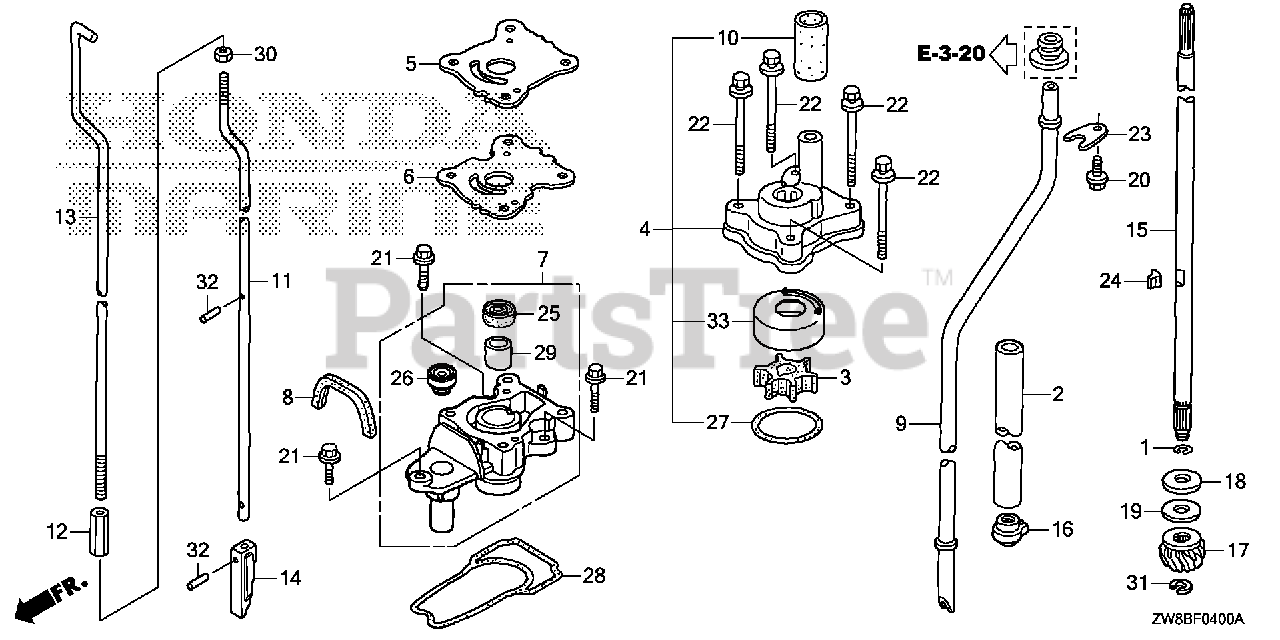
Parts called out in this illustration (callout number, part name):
1	CLIP, VALVE GUIDE
2	GUIDE, OIL (S,L)
3	IMPELLER, PUMP (S,L)
4	HOUSING ASSY., IMPELLER
5	COVER, IMPELLER
6	GASKET, IMPELLER
7	HOUSING, WATER PUMP (S,L)
8	GROMMET, WATER PUMP HOUSING
9	TUBE, WATER (S)
10	RING, WATER TUBE SEAL
11	ROD B, SHIFT (S)
12	JOINT, SHIFT ROD
13	ROD A, SHIFT (S)
14	ROD, PUSH
15	SHAFT, VERTICAL (S)
16	SLINGER, OIL (S,L)
17	GEAR, PINION
18	WASHER A, THRUST BEARING
19	WASHER B, THRUST BEARING
19	WASHER C, THRUST BEARING
20	BOLT, FLANGE (6X12) Use from Frame SN 1005249.
21	BOLT, FLANGE (6X20) (ENGINE NO.)
22	BOLT-WASHER (6X50)
23	PLATE, WATER TUBE SETTING
24	KEY, WOODRUFF
25	SEAL, WATER (13MM) (ARAI)
26	SEAL, WATER (6MM)
27	O-RING (42.2X2.4)
28	O-RING, WATER PUMP HOUSING
29	BUSH (13X15X15)
30	NUT, HEX. (6MM)
31	E-RING (8MM)
32	ROLLER (2.5X11.8)
33	LINER, PUMP
